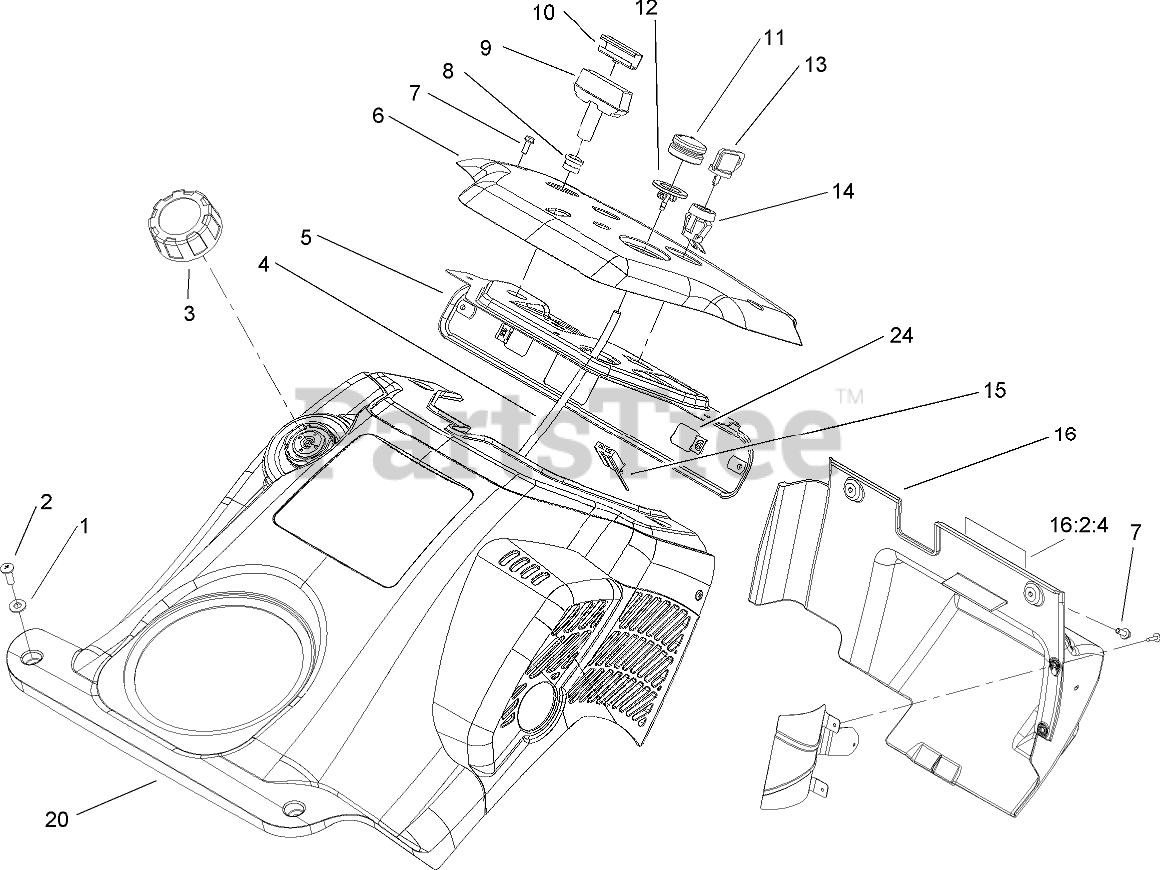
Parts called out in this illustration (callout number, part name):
1	WASHER-FLAT
2	SCREW-PPH
3	GAS CAP ASM
4	HOSE-PRIMER
5	PANEL-SUPPORT, CONTROL
6	PANEL-CONTROL
7	SCREW-HWH
8	GUIDE-ROPE, STARTER
9	HANDLE-START
10	CLIP-STARTER
11	BULB-PRIMER
12	BODY-PRIMER
13	KEY-IGNITION
14	SWITCH
15	CONNECTOR-BODY
16	LOWER SHROUD/BAFFLE W/DECAL ASM
16:2:4	DECAL
20	UPPER SHROUD ASM
24	NUT-SPEED
